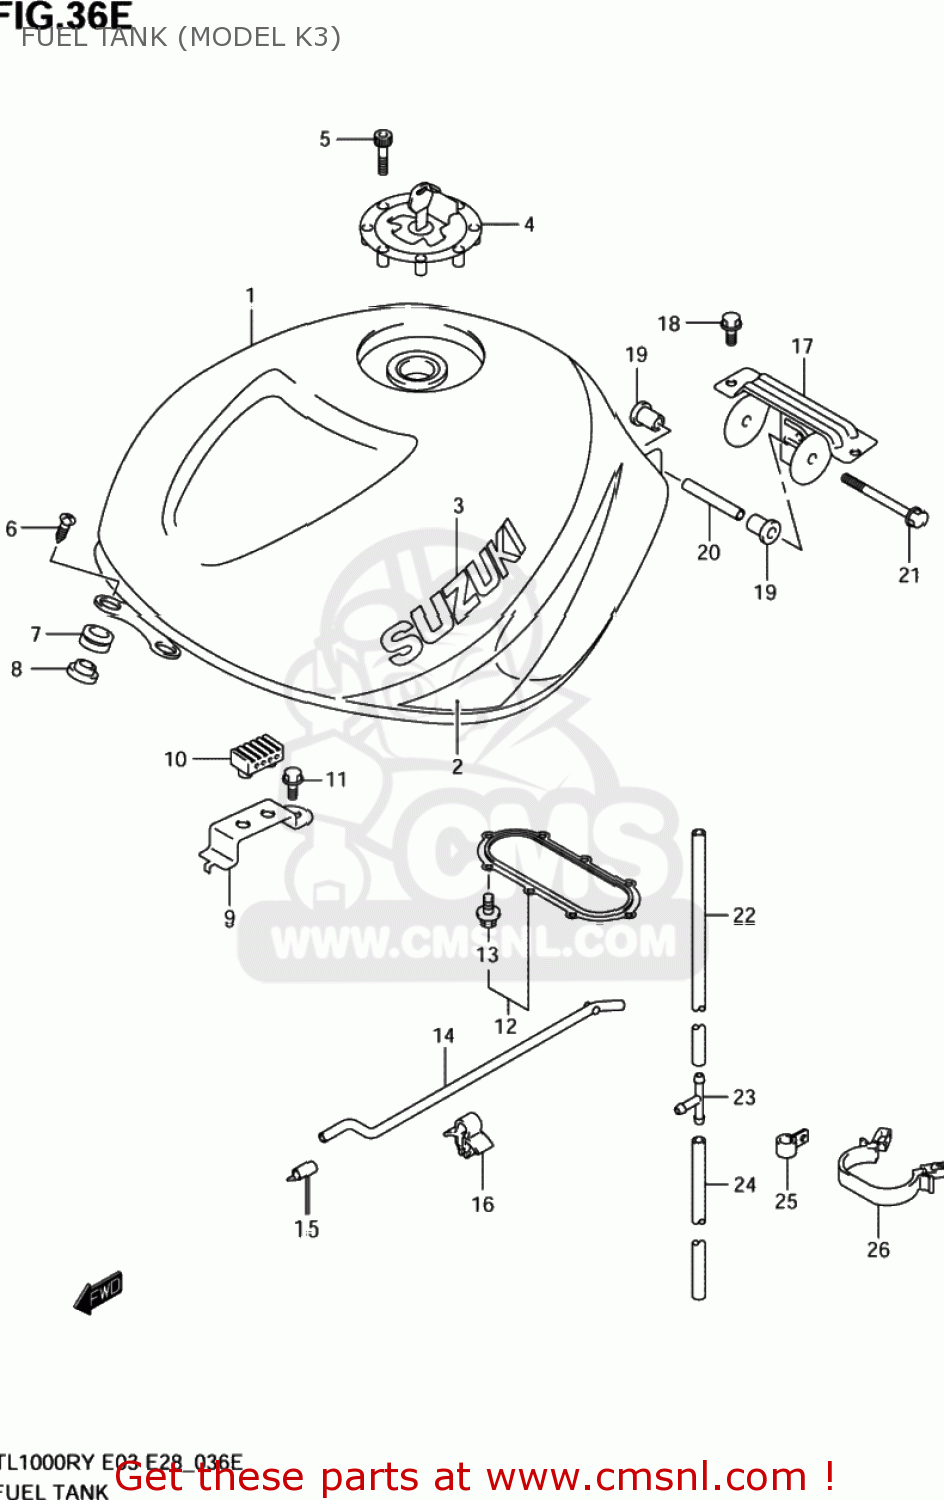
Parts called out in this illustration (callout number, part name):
1	TANK ASSY,FUEL(YELLOW)
2	TAPE SET,FUEL TANK
3	EMBLEM,FUEL TANK
4	CAP SET,FUEL TANK
5	BOLT(5X20)
6	SCREW(6X25)
7	CUSHION
8	WASHER
9	BRACKET,FUEL TANK SIDE CUSHION
10	CUSHION,SEAT(40X20X15)
11	BOLT
12	PACKING SET,FUEL PUMP (NAS)
13	BOLT(5X10)
14	STAY,FUEL TANK
15	CAP,OD:11
16	CLAMP
17	BRACKET,FUEL TANK RR
18	BOLT
19	CUSHION,FUEL TANK RR
20	SPACER,FUEL TANK RR
21	BOLT
22	HOSE,FUEL TANK DRAIN
23	3 WAY
24	HOSE(7X10.2X600)
25	CLAMP
26	CLAMP
